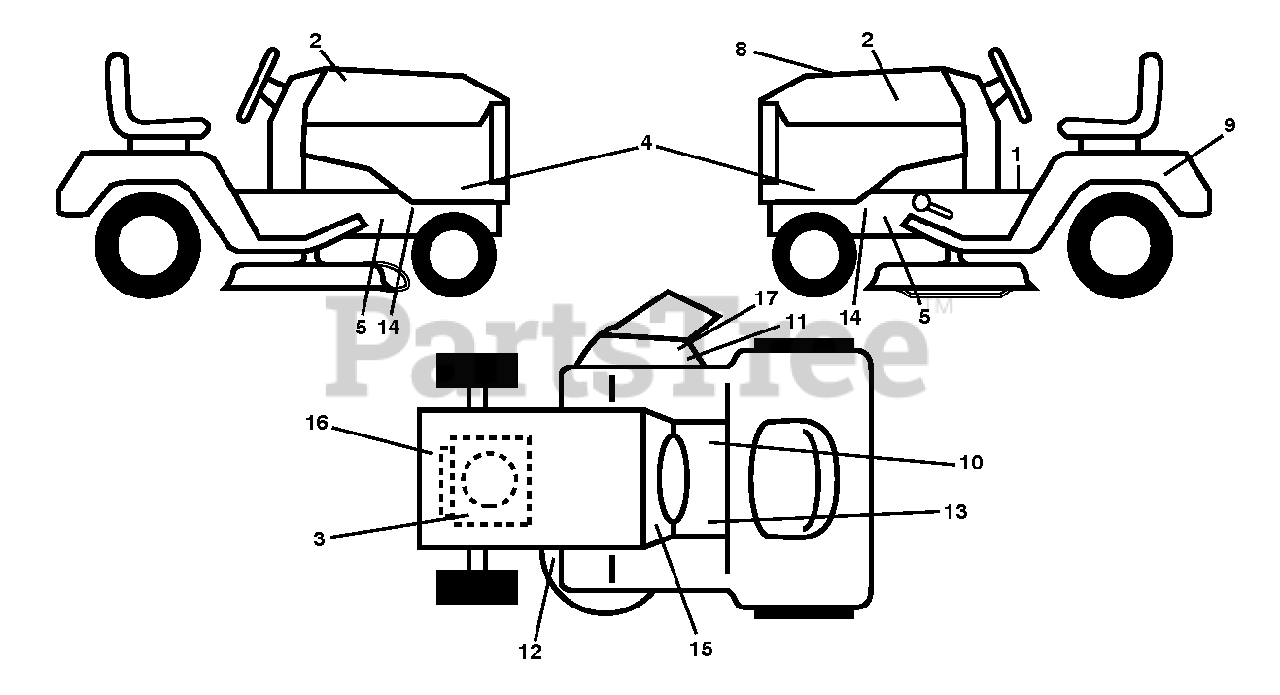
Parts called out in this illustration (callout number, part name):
1	DECAL.READ.OWN.MAN.SYMBOL.LT
2	DECAL.BADGE.170MM.TEXTLOGO.
3	DECAL.ENGINE.WARNING
4	DECAL.SDPNL.HUSQLT.TS138
5	DECAL.CHASSIS.HOT.MUFFLER
8	DECAL.RPL.BSM31.INTK.TLW.38.GE
9	DECAL BTRY SYMBOLS
10	DECAL.PARKING.BRAKE.SADDLE.LT
11	DECAL.DFLCTR.WARNNG.CTFNGR.SYM
12	DECAL.DECK.SCH.36,38,94.NONCR
13	DECAL.FNDR.SDLE.BRAKE.CLUTCH.6
14	DECAL.WARNING.SERVCE/FIRE
15	DECAL.SNOWFLAKE.MS498.HUSQ
16	DECAL.ENG.B&S.HS.500CC.382338
17	DECAL, DECK DEFLECTOR, WARNING
